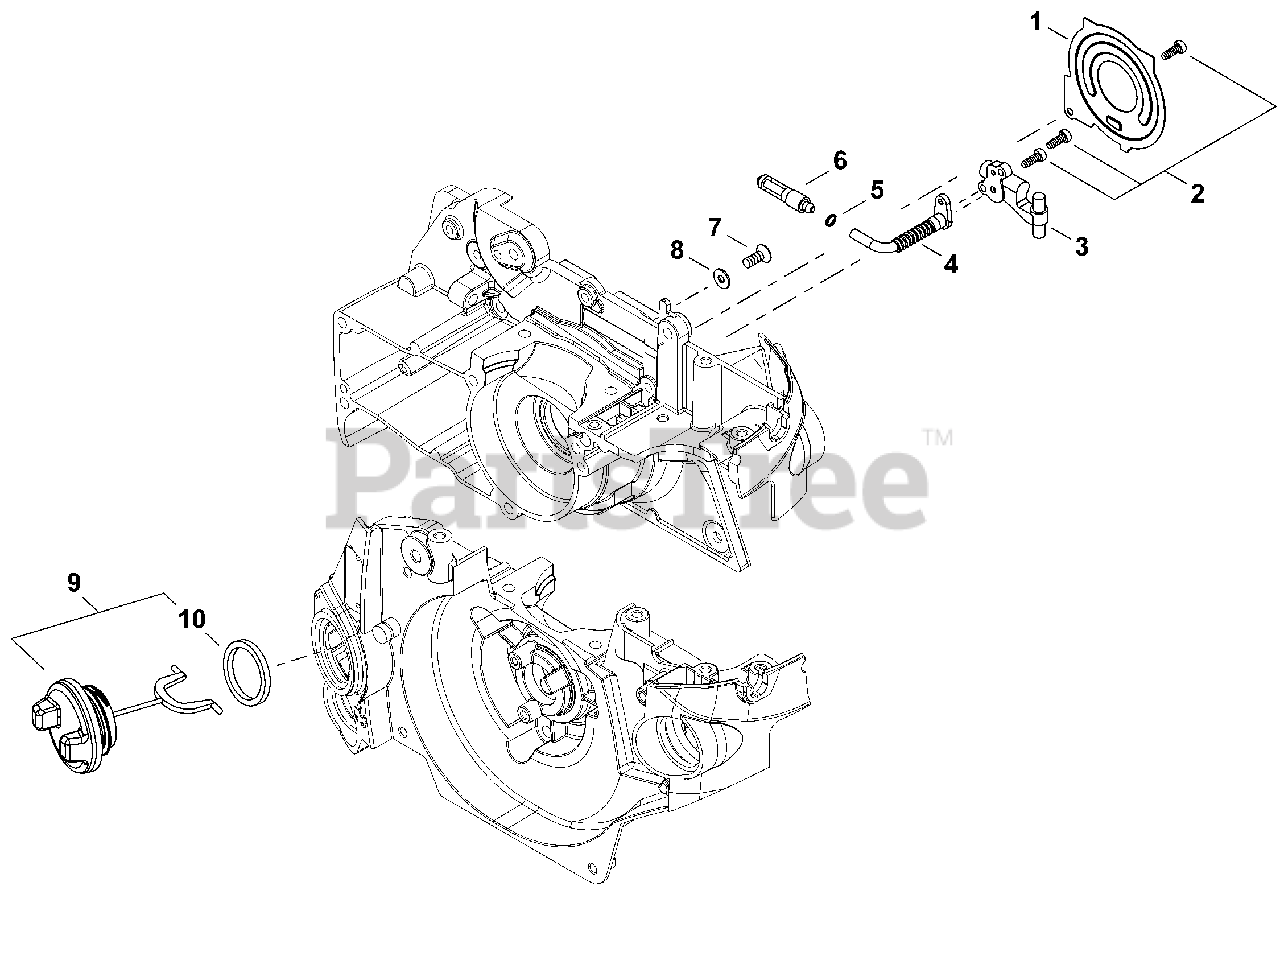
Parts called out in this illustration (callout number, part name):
1	COVER, OILER
2	BOLT, ADHESIVE M4×14
3	OIL PUMP ASSY
4	PIPE, OIL
5	CLIP Ø6
6	FILTER, OIL
7	SCREW 4×8
8	WASHER 4mm
9	CAP ASSY, OIL
10	GASKET, CAP
